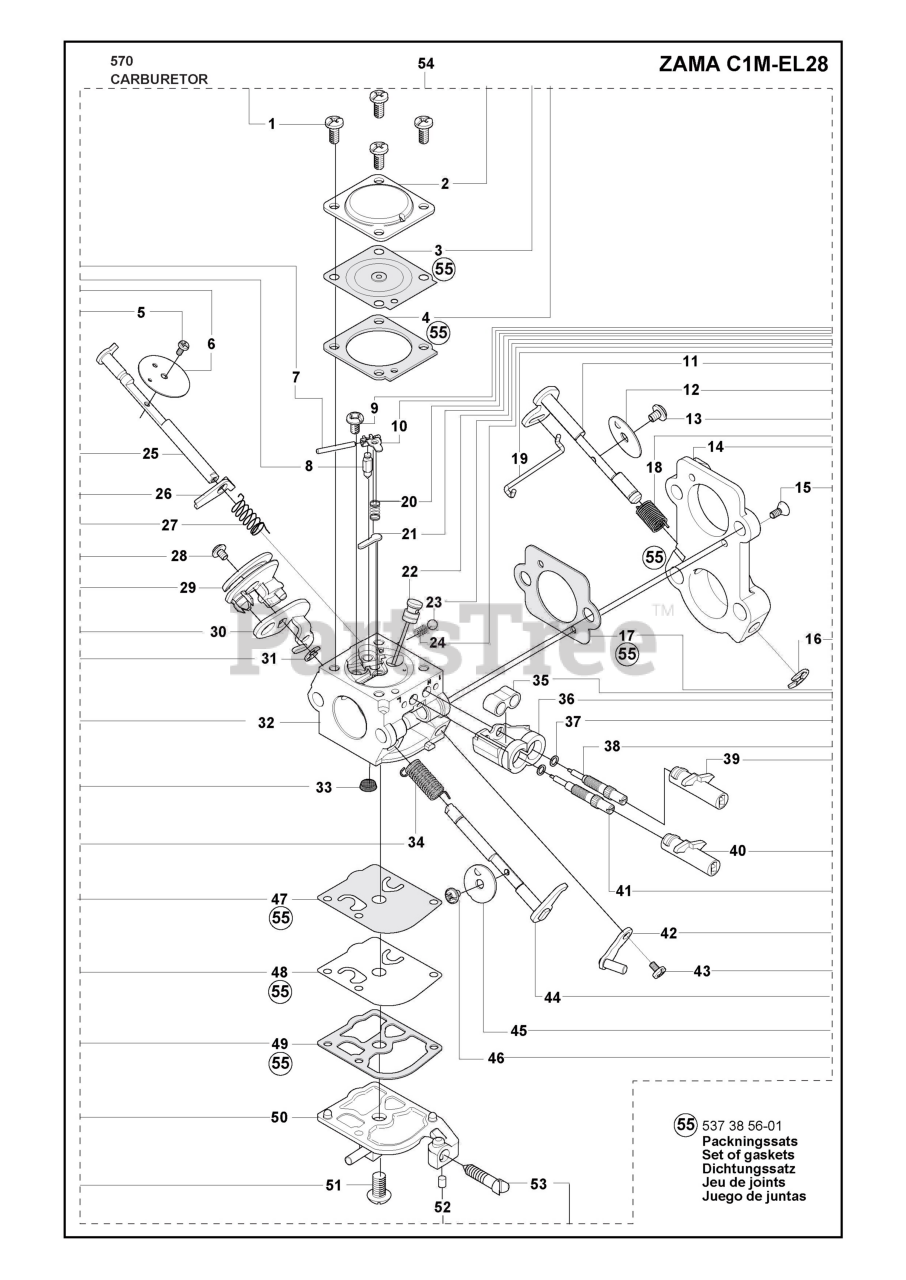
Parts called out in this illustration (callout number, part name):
6	CHOKE FLAP
7	PIN FULCRUM
8	INLET NEEDLE
12	THROTTLE FLAP
14	RP CARBURETOR
25	CHOKE SHAFT
32	RP CARBURETOR
38	NEEDLE HIGH SPEED
41	LOW SPEED NEEDLE
44	THROTTLE SHAFT
47	PUMP DIAPHRAGM
54	RP CARBURETOR
55	GASKET SET
